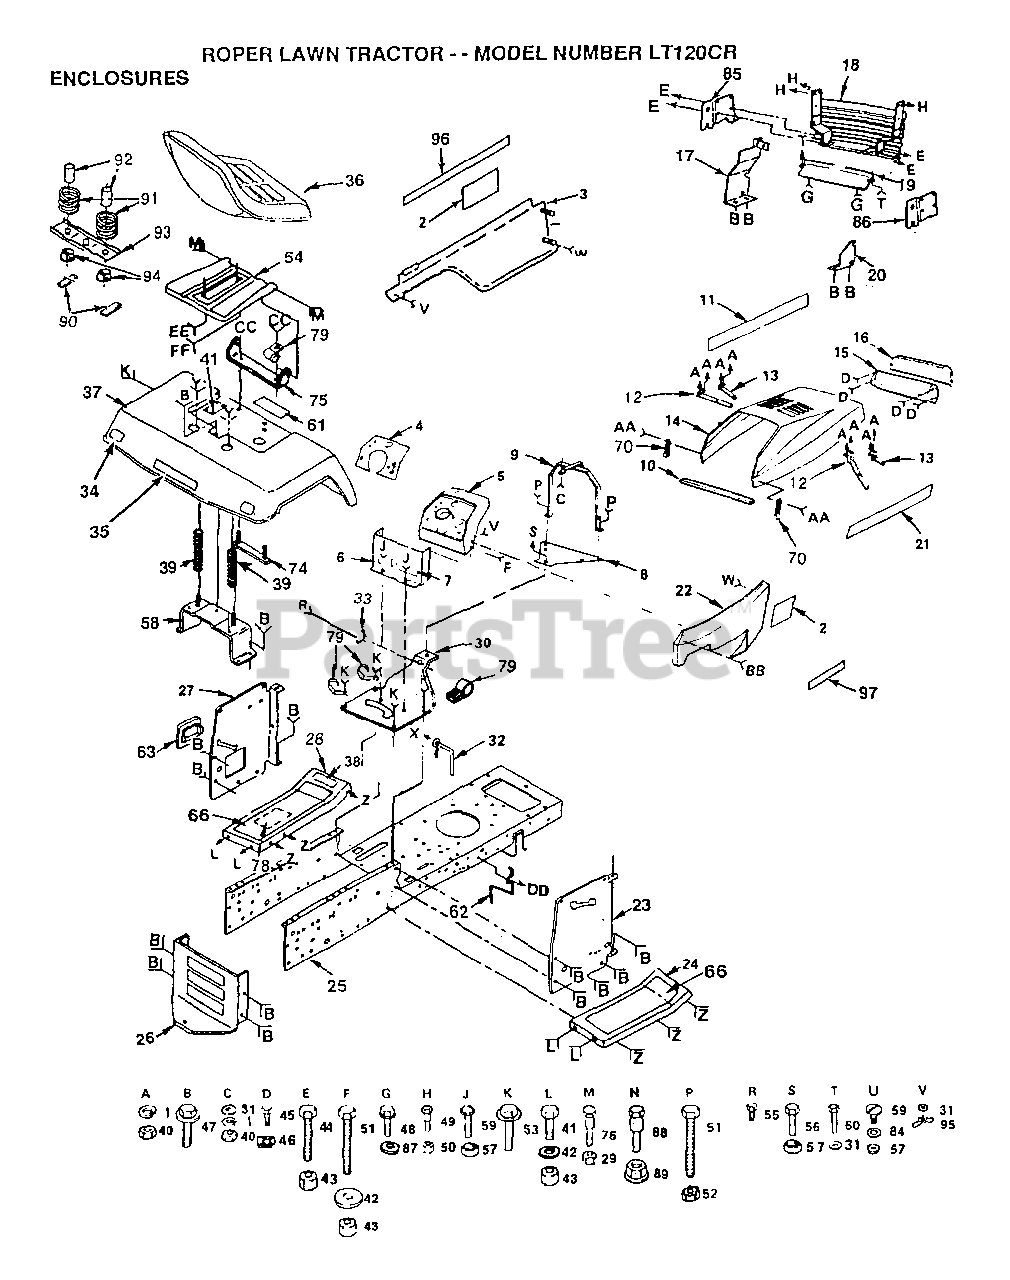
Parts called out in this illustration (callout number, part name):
1	LOCKWASHER
4	PLATE DASHBOARD
6	DASH ASSY LT
9	SUPPORT ASSY LT
16	LENS LT
20	SUPPORT LH YTH
23	PANEL DASH RH YT
25	CHASSIS ASSY
28	FOOTREST LH YT
31	WASHER PM
32	BELT GUIDE
34	REFLECTOR-TAIL YT
38	DECAL T
42	WASHER
44	BOLT
46	"""J"" FASTENER LT"
47	SCREW
48	SCREW
49	BOLT T
52	NUT
53	SCREW LT
56	BOLT
59	SCREW
60	SCREW HEX CRT
61	DECAL
62	BELT GUIDE
63	COVER ACCESS
70	HOOD LATCH T
79	CLIP T
84	WASHER
85	SUPPORT LH YTH
86	SUPPORT RH YTH
87	WASHER
88	BOLT
89	NUT T
90	STRIP FORM
91	SPRING
92	SPACER SPLIT
93	BRKT SWITCH
94	BUSHING
97	DECAL SIDE PANEL
